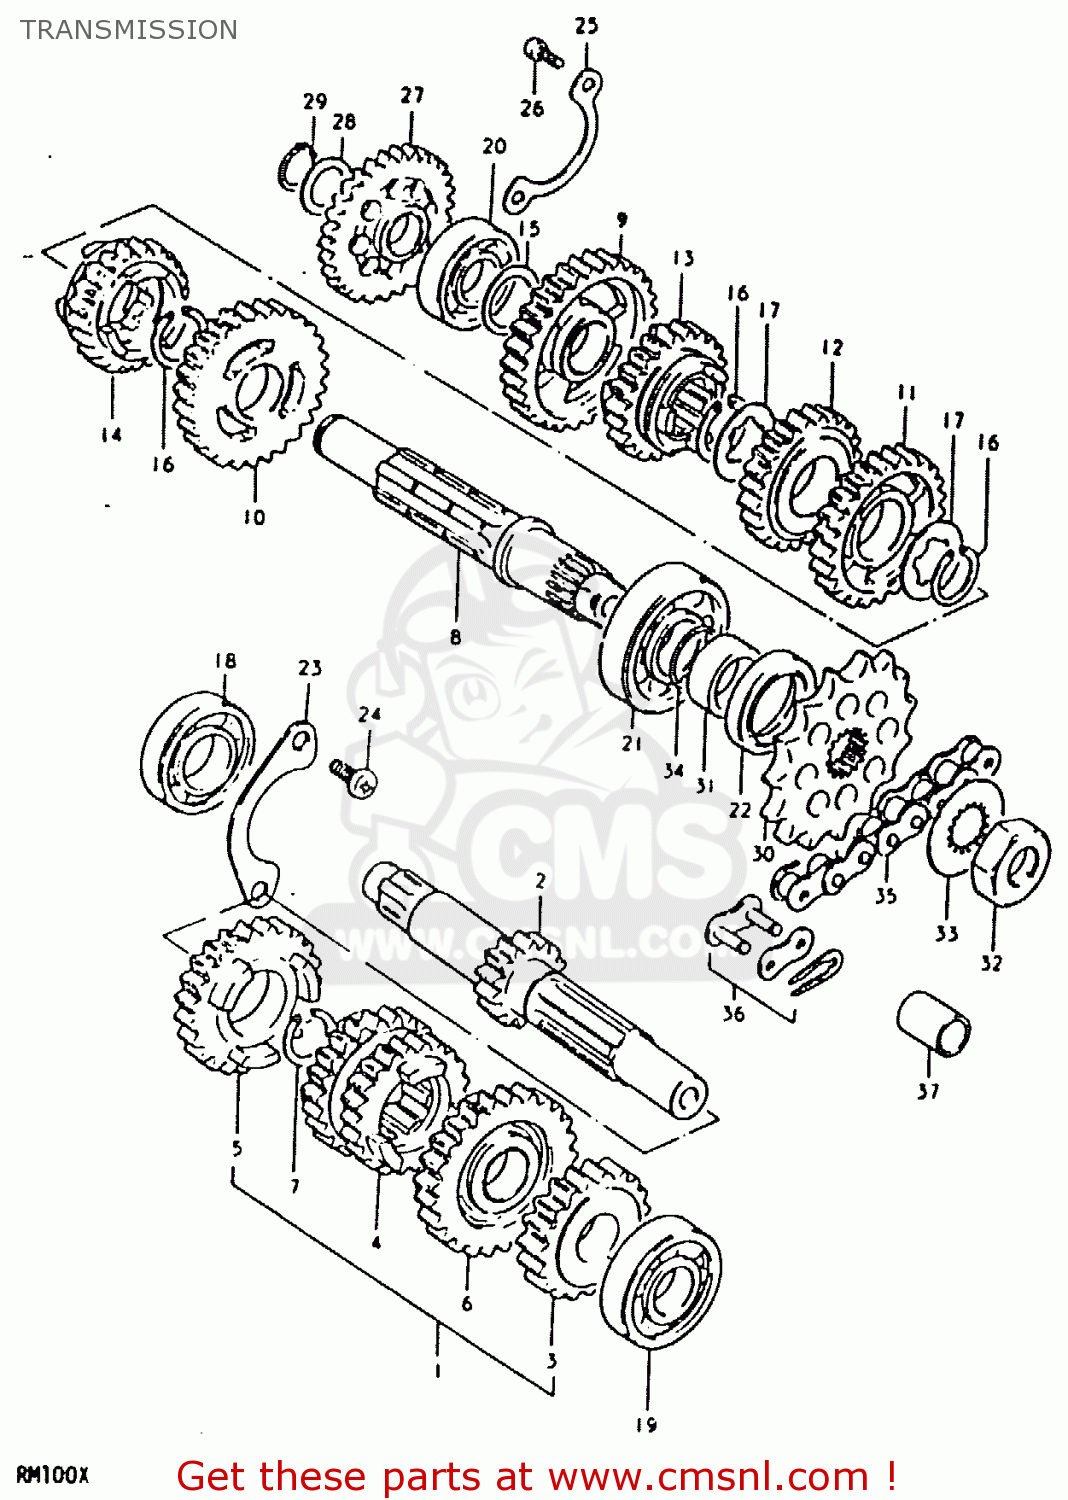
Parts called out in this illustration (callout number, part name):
1	SHAFT,COUNTER
2	SHAFT,COUNTER
3	GEAR,SECOND DRIVE
4	GEAR,THIRD DRIVE
5	GEAR,FIFTH DRIVE
6	GEAR,SIXTH DRIVE
7	CIRCLIP
8	SHAFT,DRIVE
9	GEAR,FIRST DRIVEN
10	GEAR,SECOND DRIVEN
11	GEAR,THIRD DRIVEN
12	GEAR,FOURTH DRIVEN
13	GEAR,FIFTH DRIVEN
14	GEAR,SIXTH DRIVEN
15	WASHER,THRUST
16	CIRCLIP
17	WASHER,LOCK
18	Bearing
19	BEARING
20	BEARING, RH
21	BEARING(20X47X14)
22	SEAL,OIL(25X40X7)
23	RETAINER,CNTR SHAFT BEARING
24	SCREW 6X12
25	PLATE,DRIVESHAFT BEARING
26	SCREW
27	GEAR,KICK STARTER IDLE
28	WASHER,THRUST
29	CIRCLIP,15MM
30	SPROCKET,ENGINE
31	SPACER(20X25X12.5)
32	NUT
33	WASHER,LOCK
34	O RING(D:1,ID:19.5)
35	CHAIN ASSEMBLY,DRIVE
36	JOINT(RK)
37	CUSHION
